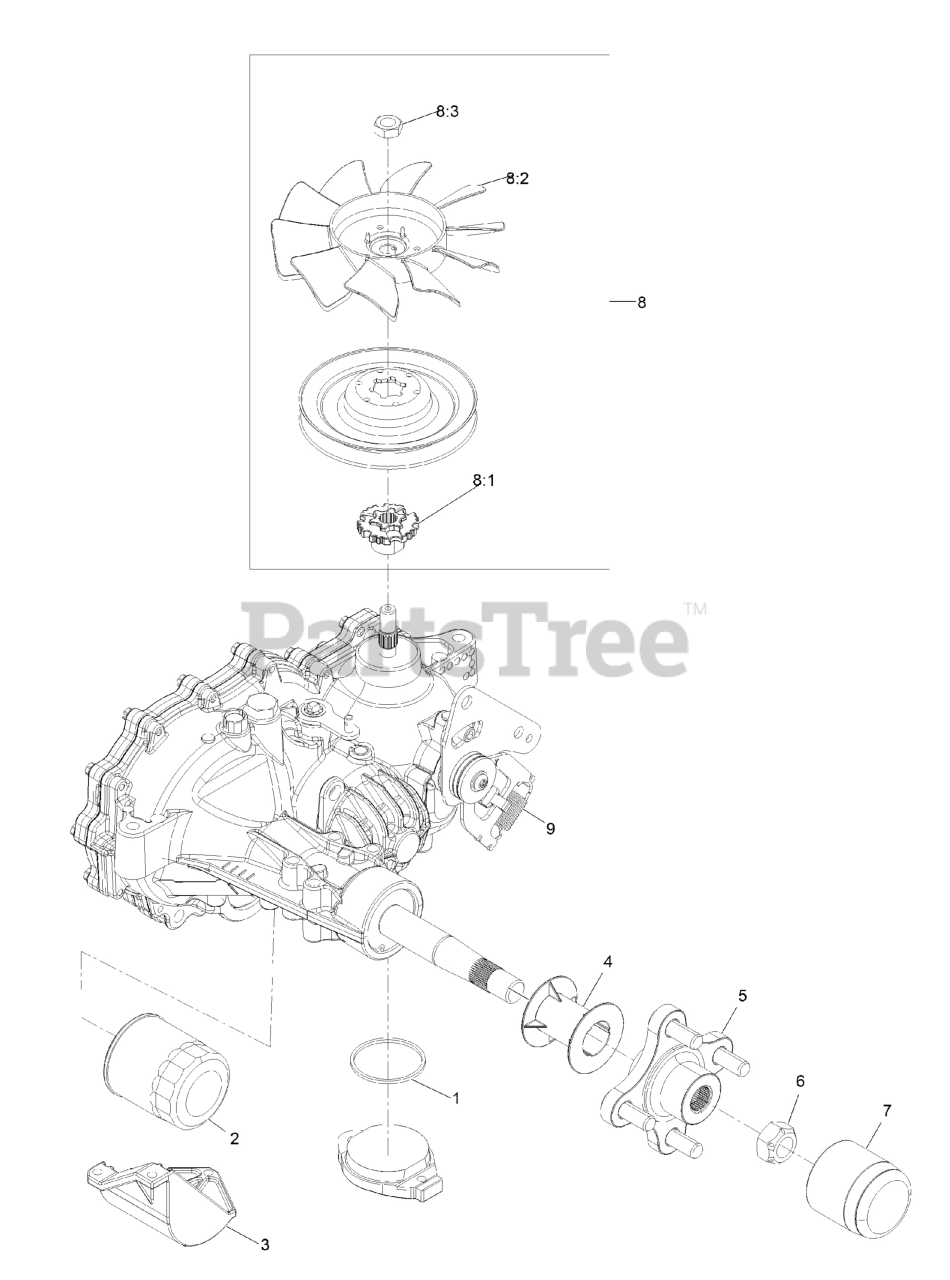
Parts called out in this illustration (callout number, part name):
1	O RING-SEAL
2	ELEMENT-OIL FILTER, HYD
3	GUARD-FILTER, RH
4	TUBE-AXLE
5	HUB-OFFSET
6	NUT-HUB
7	CAP-AXLE, LONG
8	FAN AND PULLEY KIT
8:1	HUB-FAN
9	SPRING-EXTENSION
